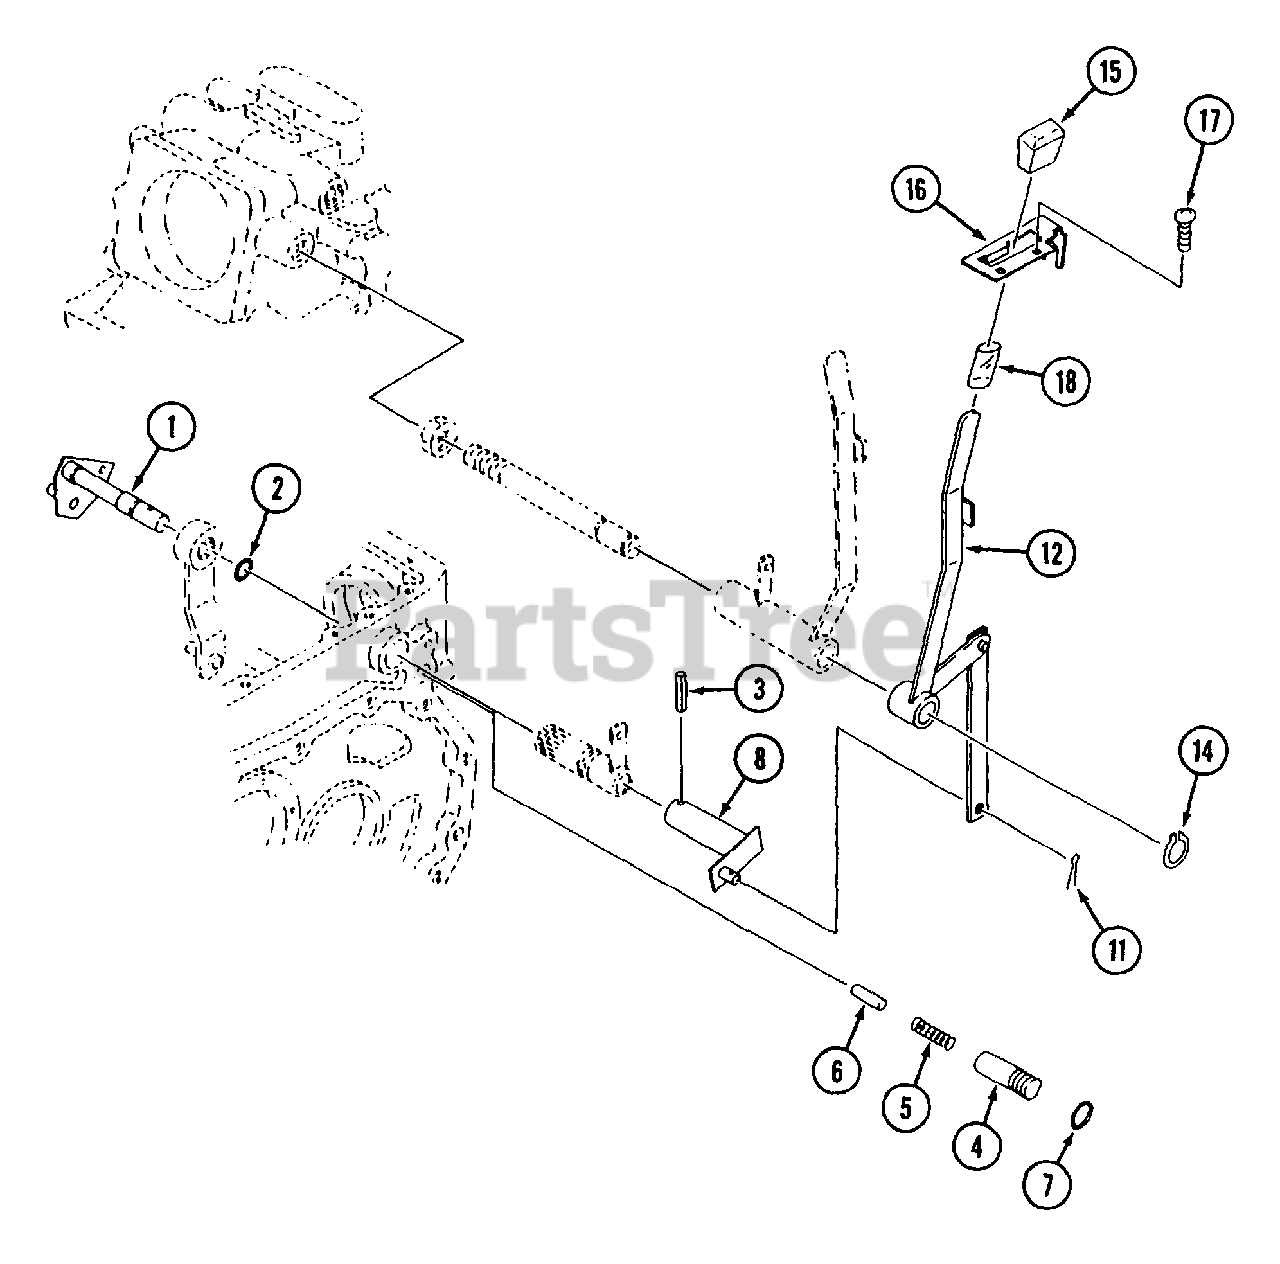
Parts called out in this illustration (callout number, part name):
3	Pin, Spring
11	Pin, Split
12	Lever, Mid PTO
16	Plate, Mid PTO
